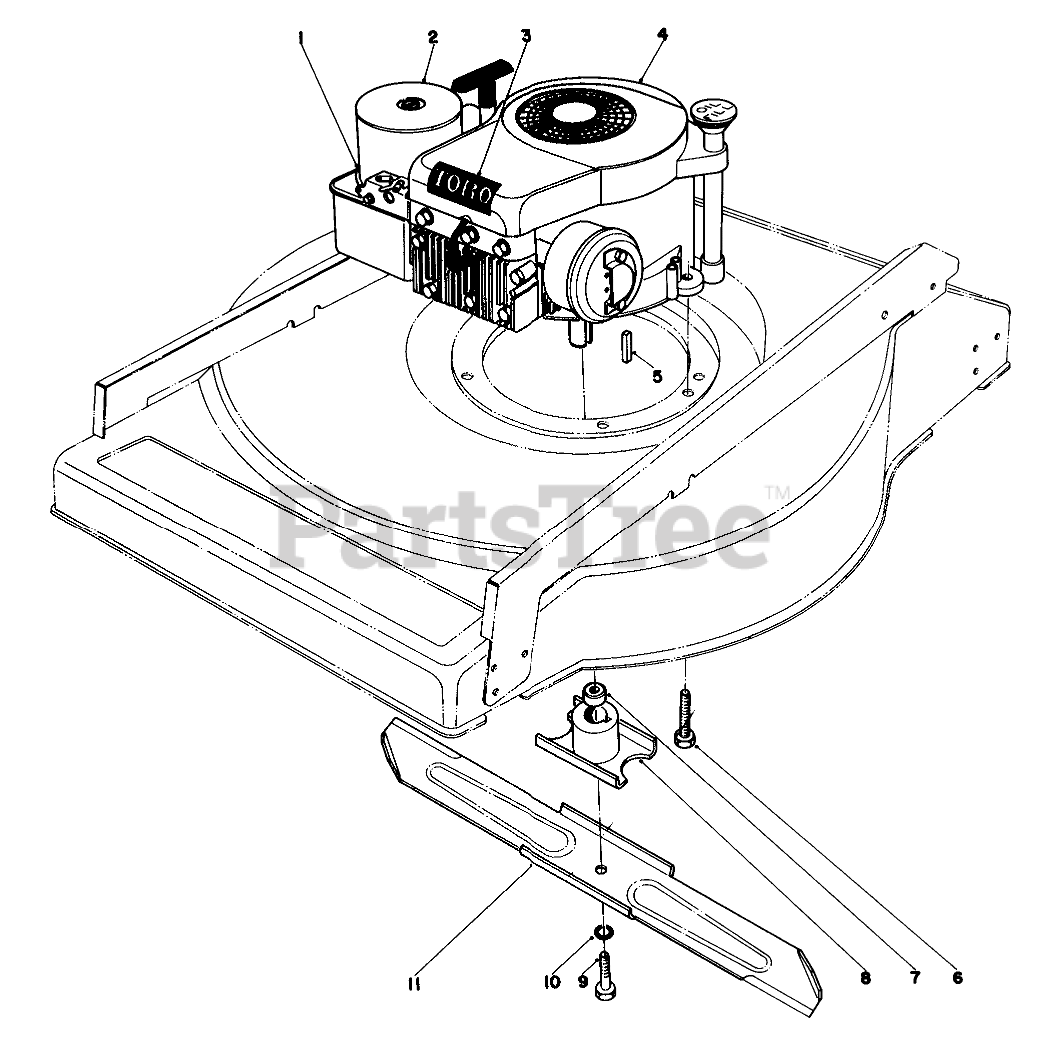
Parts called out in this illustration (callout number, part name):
1	AIR CLEANER BASE
2	Air Cleaner Cover
3	Decal
4	Engine
5	KEY-SQUARE
6	SCREW-HWHTF
7	SPACER,BLADE RETAINER
8	BLADE RETAINER WA
9	BLADE SCREW
10	WASHER-LOCK
11	Blade
